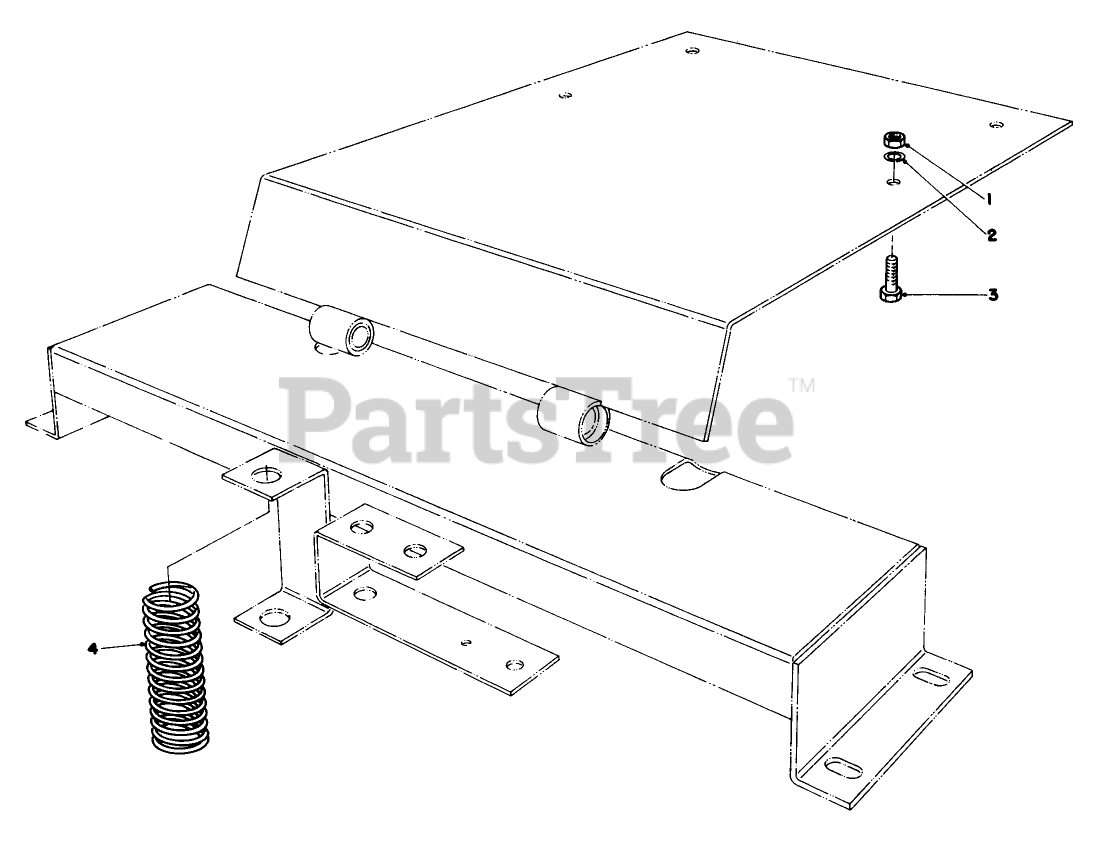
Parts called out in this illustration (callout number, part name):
1	NUT-HEX
2	WASHER-LOCK/SP
3	SCREW-HH
4	COMP SPRING
